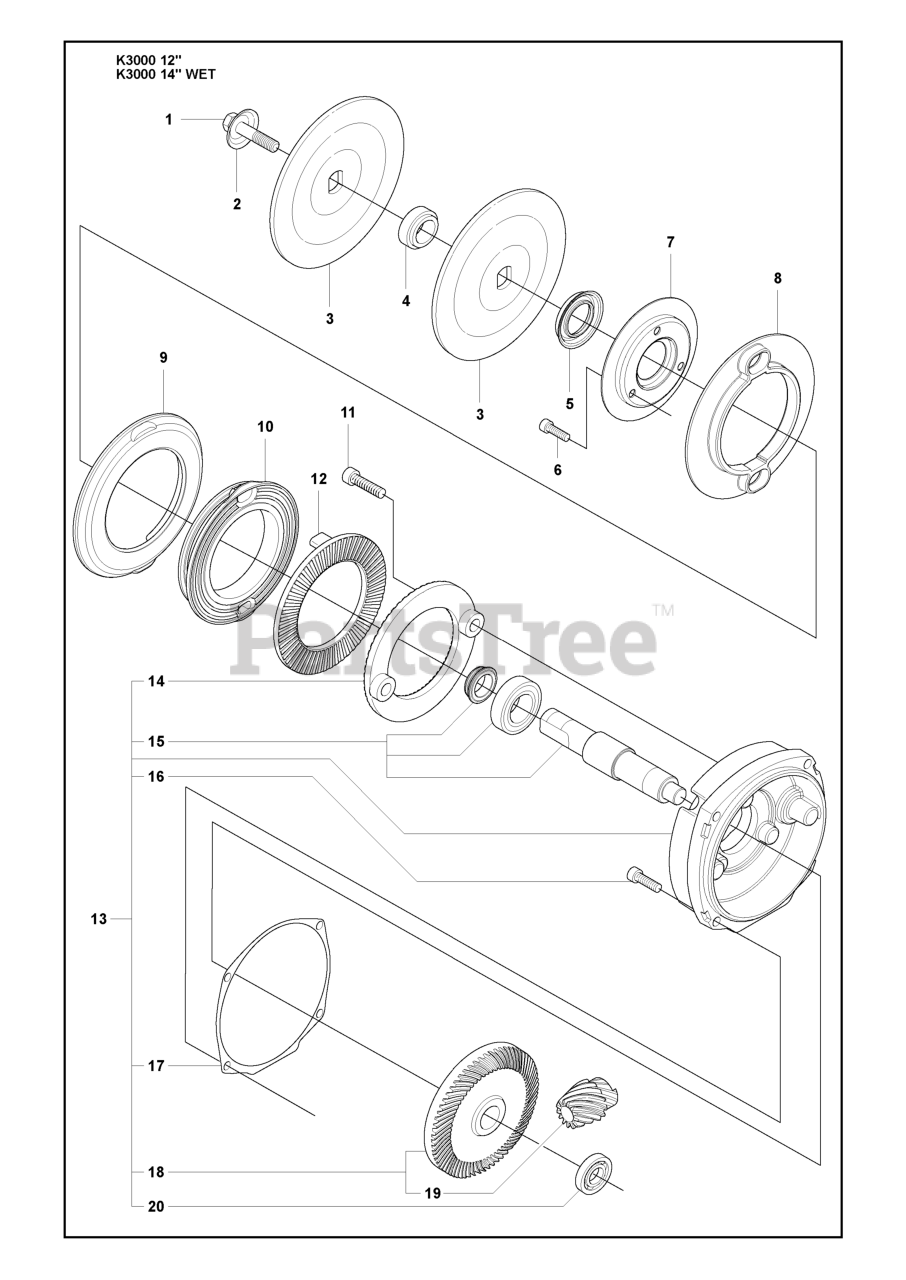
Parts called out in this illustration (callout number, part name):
1	SCREW
2	WASHER
4	BUSHING
4	BUSHING-30MM
6	SCREW ITXSCM
8	Spacer Ring Inner
9	Spacer Ring Outer
13	GEAR SET
15	SHAFT
16	SCREW ITSXCM
17	GASKET
18	GEAR CPL.
20	BALL BEARING
